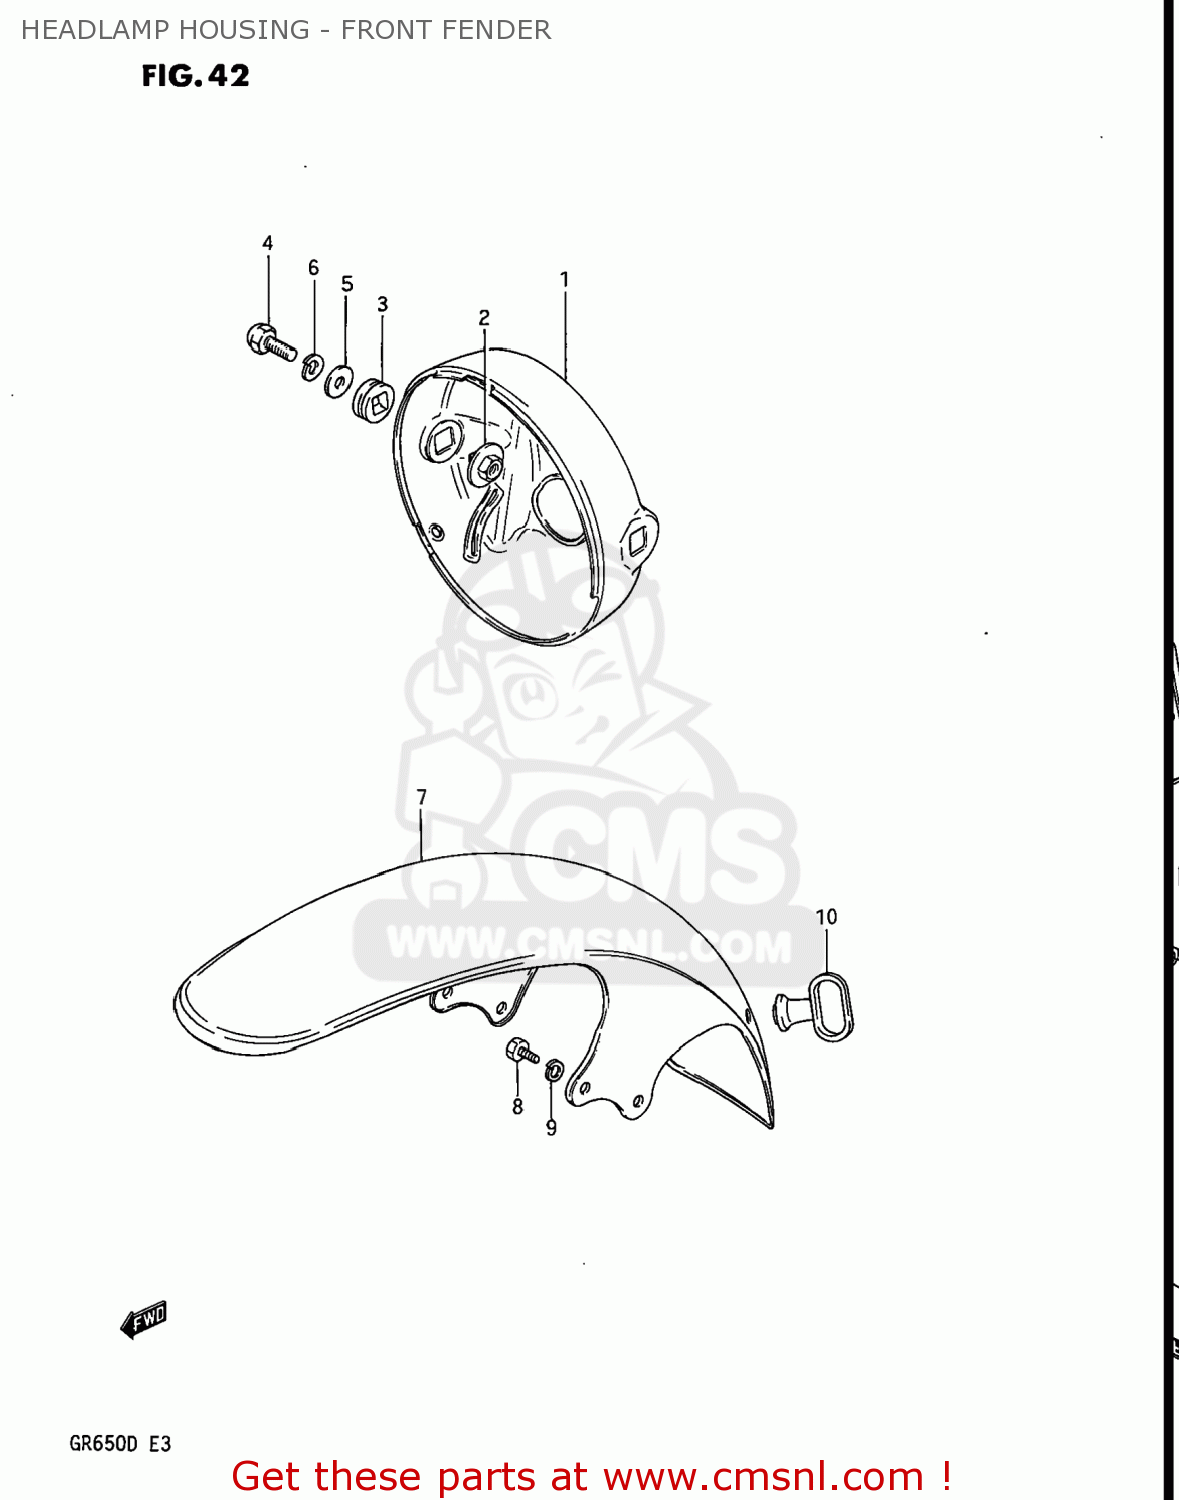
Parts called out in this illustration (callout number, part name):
1	HOUSING ASSEMBLY,HEADLAMP
2	SPACER,HEADLAMP HOUSING
3	CUSHION,HEADLAMP HOUSING
4	BOLT
5	WASHER
6	LOCK WASHER
7	FENDER,FRONT
8	BOLT
9	LOCK WASHER
10	GUIDE,CABLE
